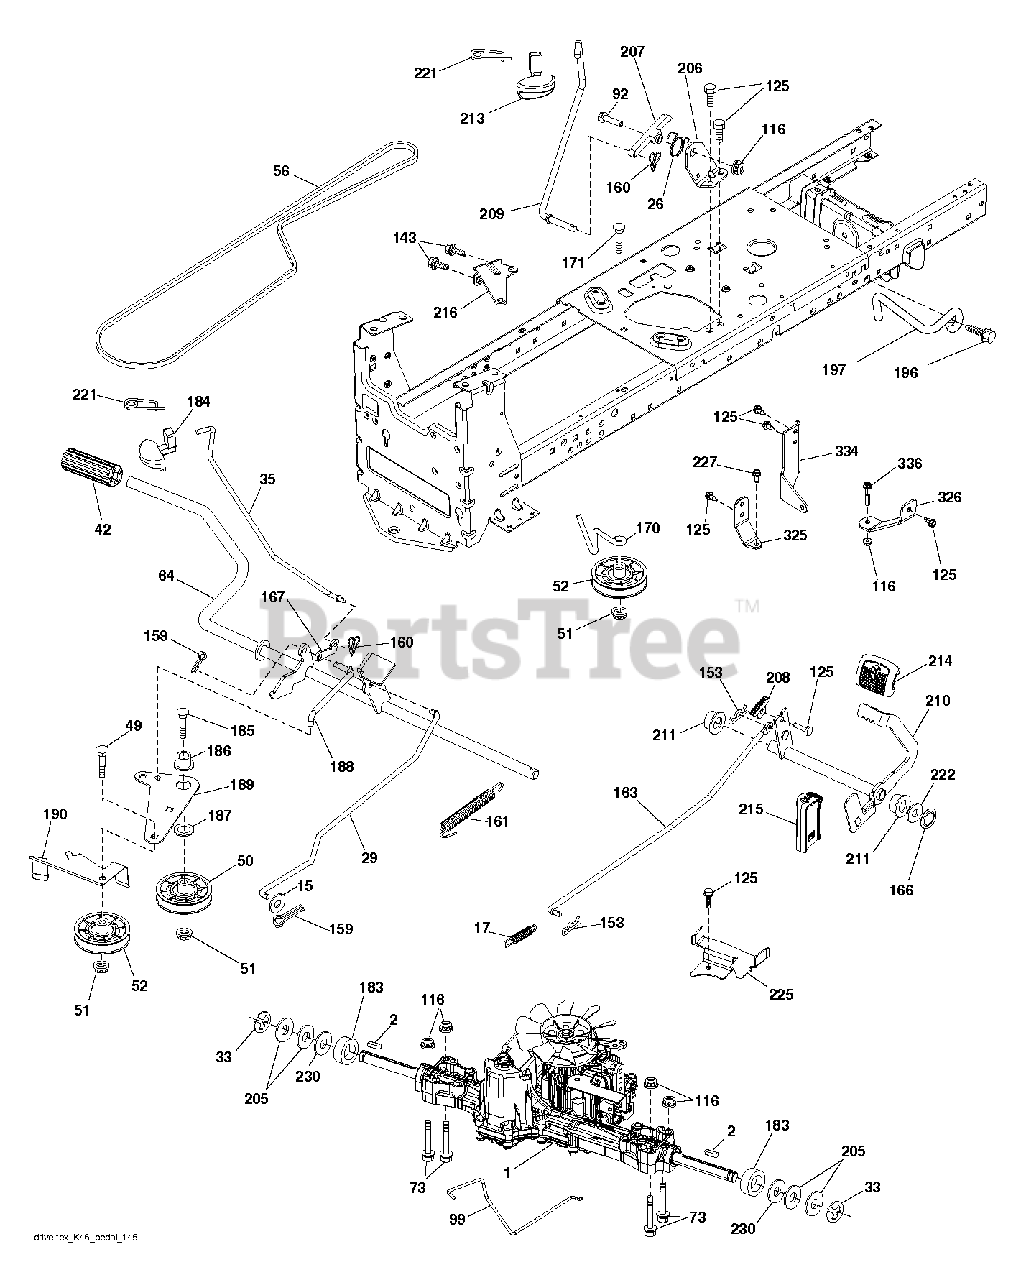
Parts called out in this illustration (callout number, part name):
2	SQUARE KEY
17	SPRING.BRAKE.K46.GREEN
26	SPRING.RETURN.CRUISE
29	ROD.BRAKE.K46
33	E-RING LT
35	Parking Brake Rod, GT Husq
42	PEDAL COVER T
49	BOLT
50	IDLER.FLAT.910.OFFSET
51	NUT LOCK FLG 3/8-16 UNC
52	IDLER.V-GROOVE.910.OFFSET
64	SHAFT.ASM.PEDAL.BRK.CNTR
92	BOLT
99	ROD.SPRING.BYPASS.K46.LT.Z
116	NUT LOCK HEX FLANGE 5/16-18
125	SCREW
153	RETAINER M
159	COTTER PIN
160	RETAINER CLIP
161	SPRING, RETURN LT
166	NUT.PUSH.625
167	LATCH.BRAKE.SPRING
170	KEEPER.V-IDLER.CENTER.
171	BOLT
183	SPACER AXLE
184	Parking Brake Handle, Black
186	SPACER.RETAINER
187	WASHER 12/32X2X10GA
188	LINK.CLUTCH.GROUND.DRIVE
189	BELLCRANK.GROUND.DRIVE.TEX.
190	KEEPER.BELLCRANK.DRIVE
196	SCREW 3/8-16X1
197	LINK.CLUTCH.ANIT-ROTAT
207	LATCH.CONTROL.CRUISE
208	GEAR.SECTOR.CONTROL.CR
209	ROD.CONTROL.CRUISE.GT.
210	ROCKER.ASM.PEDAL.CONTR
211	BEARING.NYLON
213	KNOB.CONTROL.CRUSIE.HU
214	PAD PEDAL FORWARD
215	PEDAL.REVERSE.TEX.GT.4
216	BRACKET.PULLEY.IDLER.W/TEX
221	RETAINER.SPRING.CLIP.H
222	WASHER 21/32 X 1-1/4 X 10 GA.
225	KEEPER.BELT.TRANSAXLE.K46
227	SCREW
230	WASHER.HARDENED
325	Torque Strap Bracket, 46 20" Tire LH
326	Torque Strap Bracket, 46 20" Tire RH
334	Sway Rod Bracket, K46 X431
336	Flanged Hex Bolt, 5/16-18 X 1-3/4
